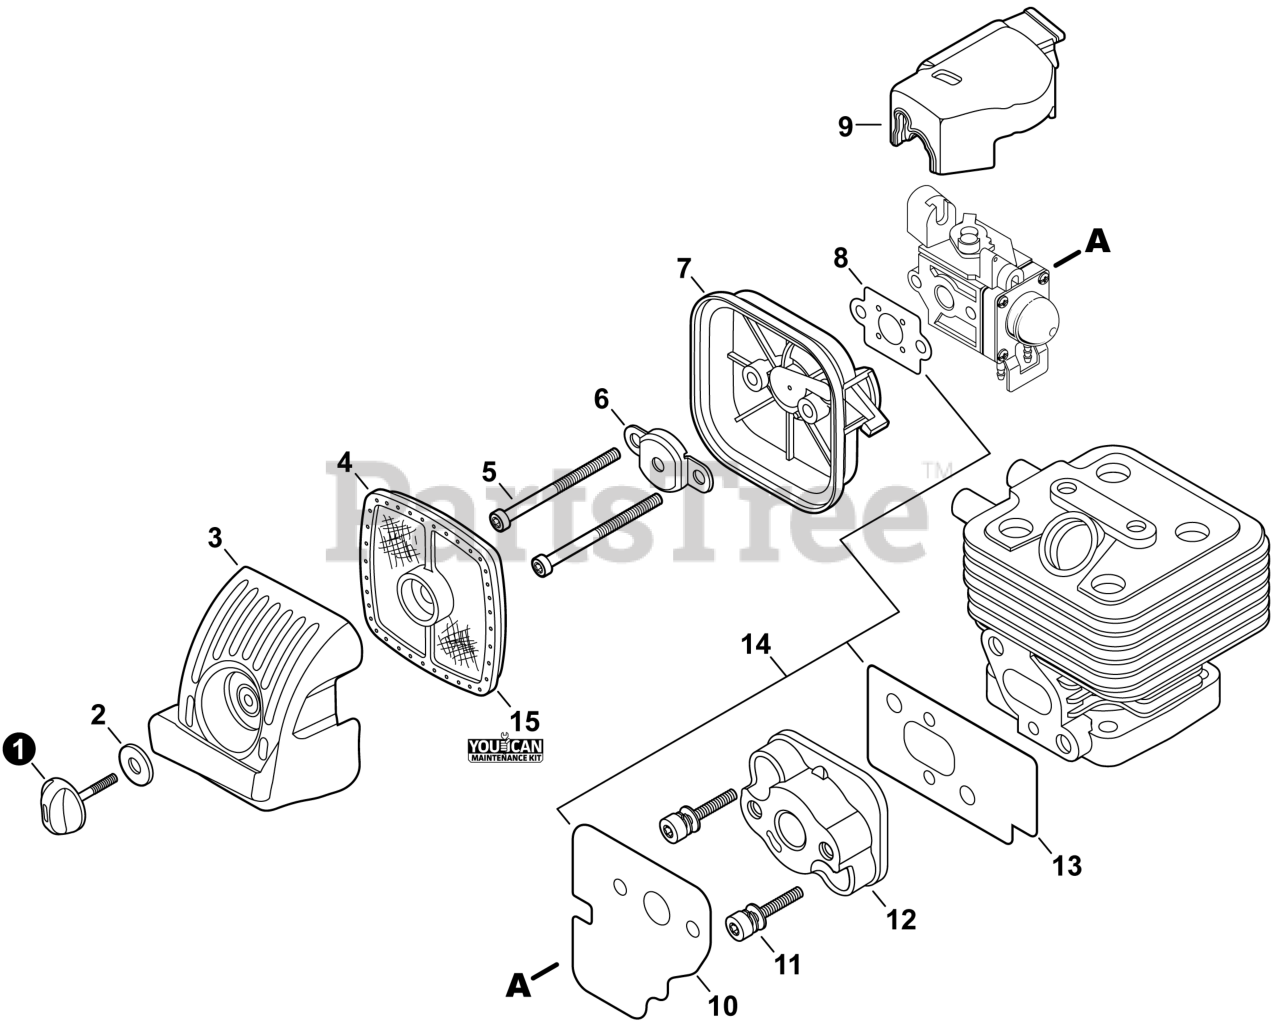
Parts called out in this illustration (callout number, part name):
1	THUMBSCREW
2	WASHER 5.5x16x0.8
3	COVER, AIR FILTER
4	FILTER, AIR - DOUBLE LAYER
5	BOLT 5x60
6	PLATE, PREVENT
7	CASE ASSY, AIR FILTER
8	GASKET, INTAKE
9	COVER, DUST
10	GASKET, INTAKE
11	BOLT 5x25
12	INSULATOR, INTAKE
13	GASKET, INTAKE
14	GASKET KIT
15	TUNE-UP KIT - YOUCAN™
